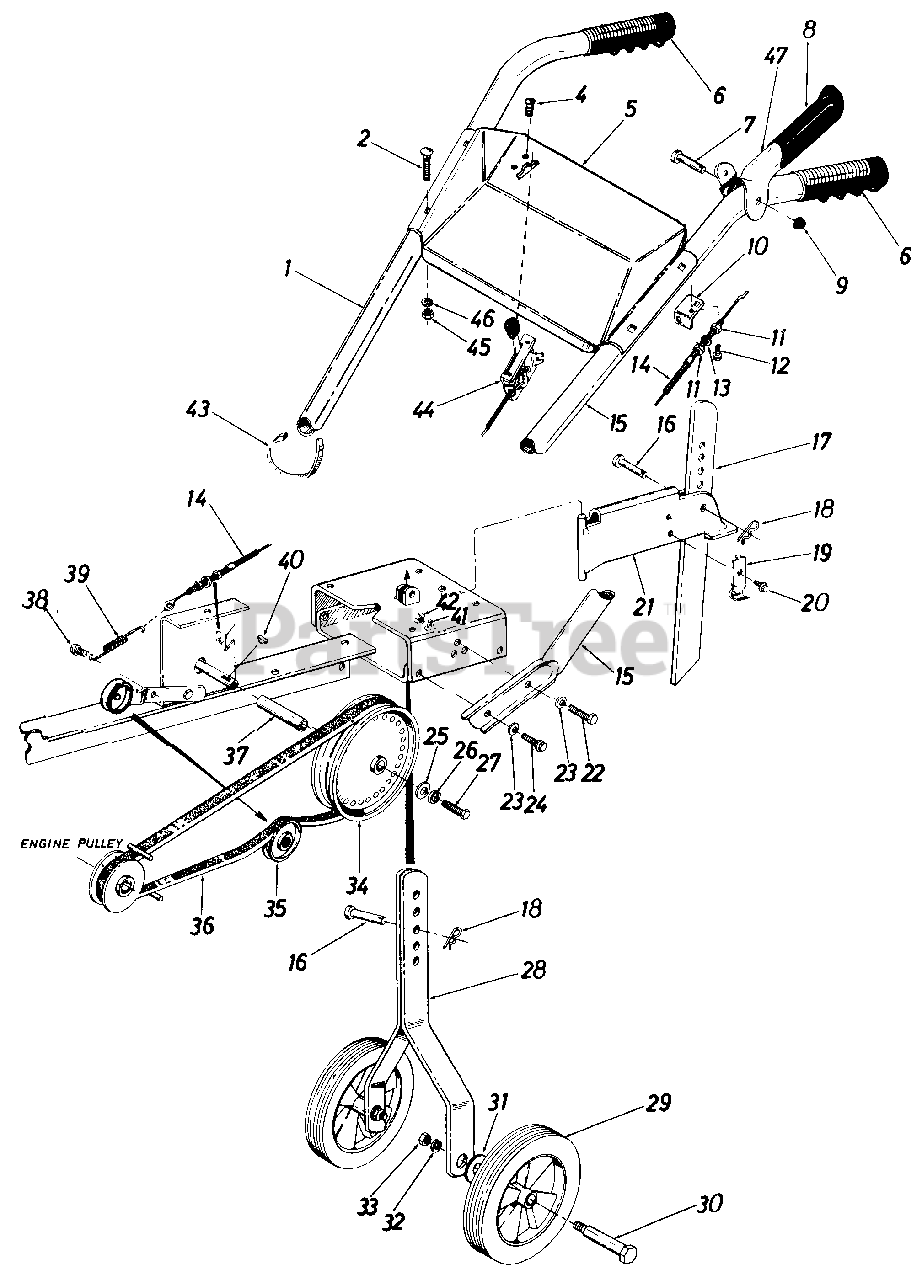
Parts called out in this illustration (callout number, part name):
1	Handle - R.H.
2	Carriage Bolt 5/16-18 x 1.75" Lg.
4	Hex Wash. Hd. AB-Tap Scr. #8 x .62" Lg.
5	Handle Panel
6	Grip
7	Clevis Pin 3/8" x 1.88" Lg.
8	Vinyl Clutch Grip
9	Push Cap
10	Cable Support Brkt.
11	Hex Jam Nut 5/16-24 Thd.
12	Hex Wash. Hd. Self-Tap Scr. 1/4-20 x .50" Lg.
13	L-Wash. 5/16" Scr.
14	Clutch Control Cable
15	Handle - L.H.
16	Clevis Pin
17	Depth Bar
18	Hairpin Cotter
19	Depth Bar Spring
20	Hex Wash. Hd. Self-Tap Scr. 1/4-20 x .50" Lg.
21	Tailpiece Ass'y.
22	Hex Scr. 3/8-16 x 1.00" Lg.
23	Belleville Wash. 3/8" I.D.
24	Hex Wash. Hd. Self-Tap Scr. 3/8-24 x 7/8" Lg.
25	Fl-Wash. .25" I.D. x .930" O.D. x .120" Thk.
26	L-Wash. 1/4" Scr.
27	Hex Scr. 1/4-28 x .75" Lg.
28	Wheel Bracket Ass'y.
29	Wheel Ass'y. 9 x 1.75
30	Shld. Bolt
31	Belleville Washer 1/2" I.D.
32	L-Wash. 1/2 Scr.
33	Hex Nut 1/2-20 Thd.
34	Pulley 6.00" O.D.
35	Idler Pulley
36	V-Belt 1/2" Pitch x 39"
38	Hex Wash. Hd. Self-Tap Scr. 5/16-18 x .75" Lg.
39	Extension Spring
40	Hi-Pro Key
41	L-Wash. 3/8" Scr.
42	Hex 3/8-16 Thd.
43	Cable Ties
44	Throttle Control Comp.
45	Hex Nut 5/16-18 Thd.
46	L-Wash. 5/16" Scr.
47	Clutch Handle Ass'y.
